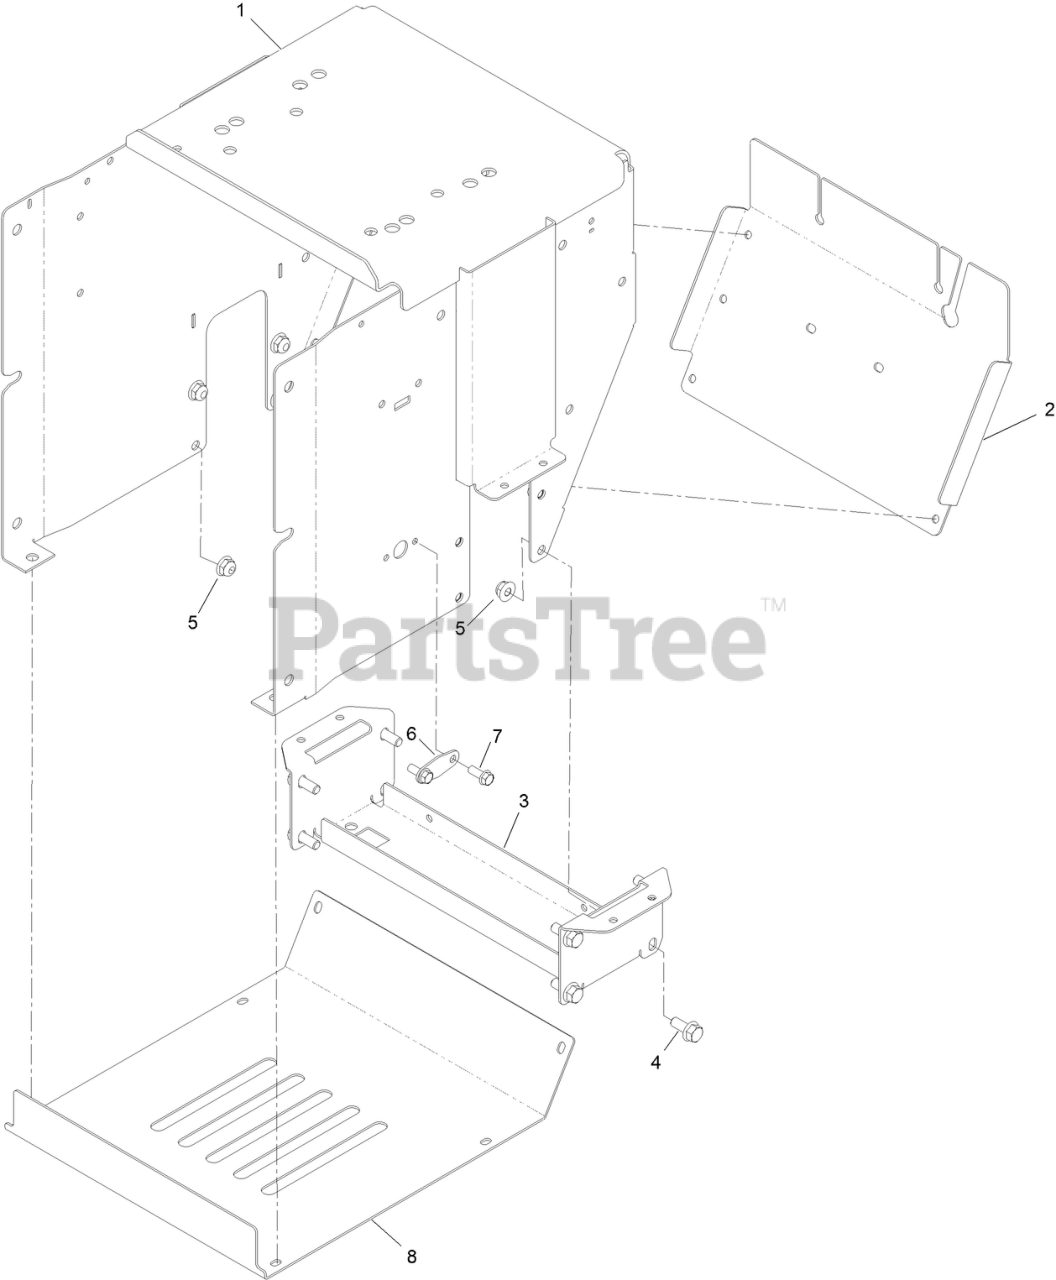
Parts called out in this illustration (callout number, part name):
1	FRAME-TRACTION
2	COVER-REAR
3	BRACE-FRAME, LOWER
4	SCREW-HHF
5	NUT-HF
6	COVER-LOCK, NEUTRAL
7	SCREW-HWH
8	COVER-BOTTOM
